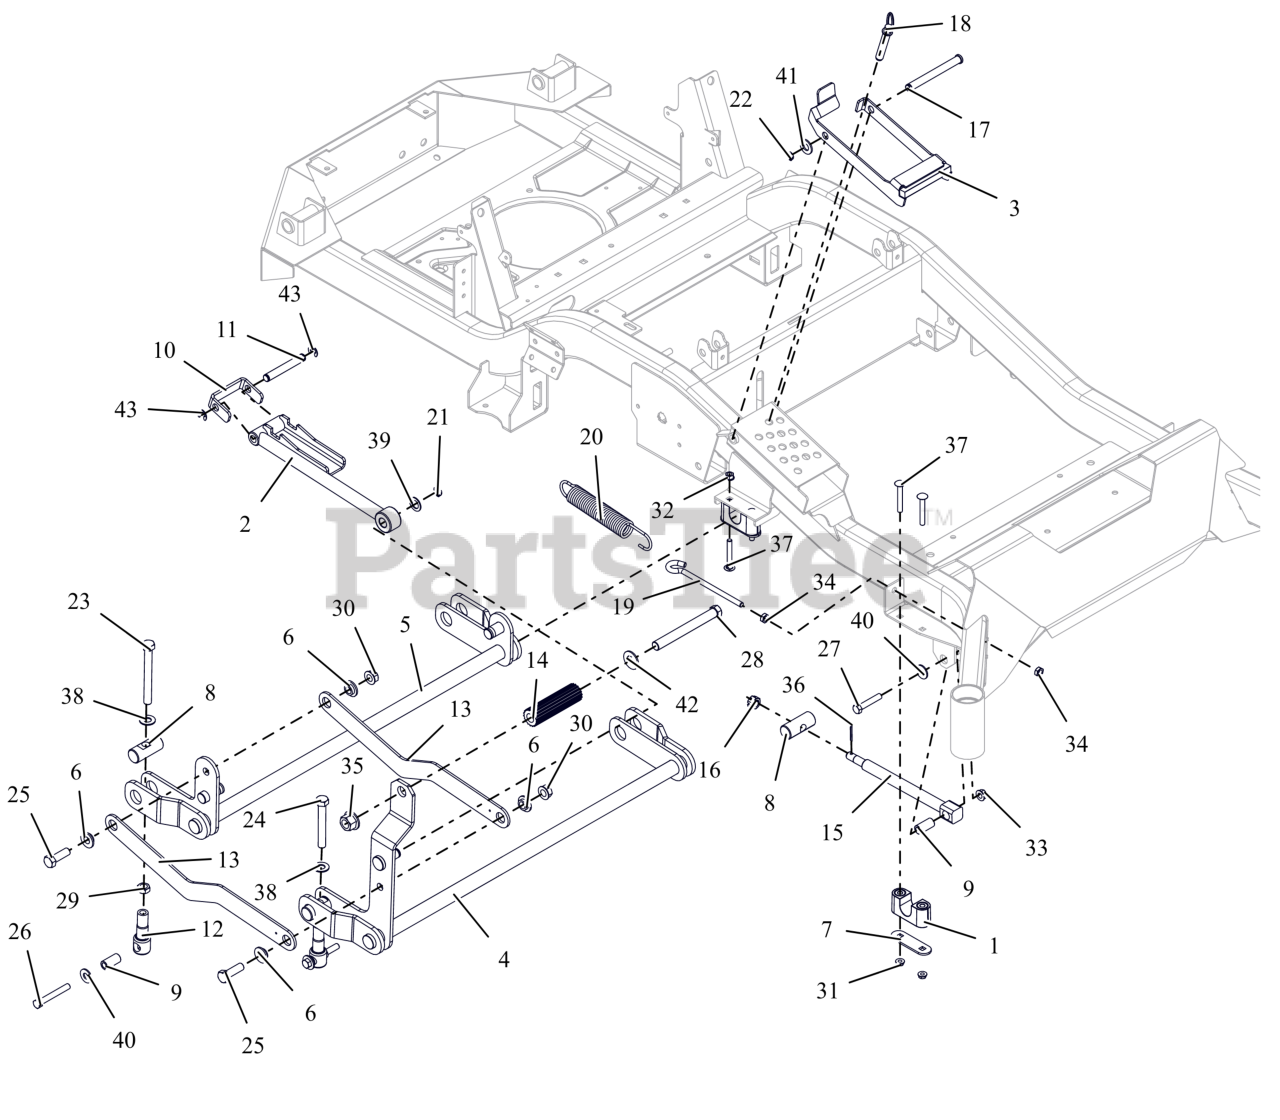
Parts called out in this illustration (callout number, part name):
1	ASM-BUSHING, DECK LIFT
2	WLDMT, HOC ARM
3	BRKT, HOC TRANSFER LOCK
4	WLDMT, FRONT DECK LIFT PIVOT
5	WLDMT, REAR DECK LIFT PIVOT
6	BSHG-FLG .515X.750X.395X1.120
7	PLATE, BEARING SUPPORT
8	PIN, DECK LIFT
9	SPACER, DECK LEVELING
10	BRKT, HOC LINE
11	ROD, HOC PIVOT
12	LINK, DECK LIFT FORMED
13	LINK, DECK LIFT
14	ROD, FOOT PEDAL (BLACK)
15	DRAG,LINK-HD
16	NUT-SL .50-13
17	PIN-CLEV .50X4.75X4.55
18	PIN, .50 X 2.20 USABLE LG BALL
19	BOLT,.38-16 X 5.25-.62 DIA EYE
20	SG-TENS .162X1.25X8.25 WLD 25
21	RG-RTNG-EXT .625X.050
22	RG-RTNG-EXT .500X.050 (SNAP)
23	BLT, HEX .50-13X4.50F G8 ZCC
24	BLT, HEX .50-13X3.50F G5 ZCC
25	BLT,HEX .50-13X1.50 G5 ZCC
26	BLT, HEX .38-16X2.75 G8 ZCC
27	BLT,HEX .38-16X2.00 G5 ZCC
28	BLT, HEX .62-11X5.50 G5 FBP
29	NUT,LK-CTR .50-13 GA ZCC
30	NUT,FLG-TOP LK .625-11 FBP
31	NUT-LK-TOP-FLG .250-20 GF ZCC
32	NUT,LK-CTR-FLG .31-18 GF ZCC
33	NUT-LK-TOP-FLG .38-16 ZC120
34	NUT,HEX .50-13 G2 ZCC
35	NUT,FLG-TOP LK .625-11 FBP
36	PIN,CTR.12X1.25EXTPRSQCT ZC120
37	BLT, RHSSN.31-18X2.25 G5 ZCC
38	WSHR, FLT .557X1.040X.102 ZCC
39	WSHR, FLT .630X1.005X.062 ZCC
40	WSHR,FLT .438X1.00X.083 ZCC
41	WSHR,FLT .531X1.062X.095 ZCC
42	WSHRFLT 5/8SAE CARBHARD FBP
43	RG-RTNG-EXT .500X.042 (E)
